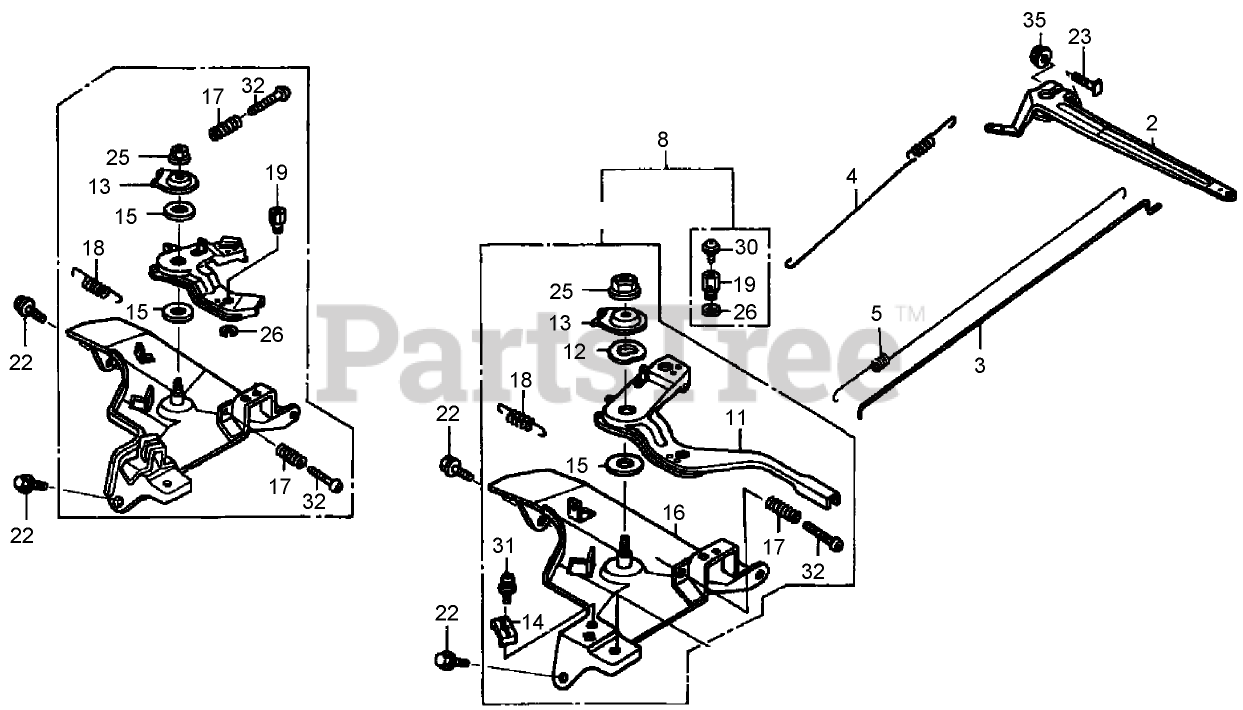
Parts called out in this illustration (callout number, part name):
2	ARM-GOVERNOR
3	ROD-GOVERNOR
4	SPRING-GOVERNOR
5	SPRING-THROTTLE RETURN
8	CONTROL ASM (REMOTE)
11	LEVER-CONTROL
12	SPRING-LEVER
13	WASHER-CONTROL LEVER
14	Holder-Cable
15	SPACER-CONTROL LEVER
16	BASE-CONTROL
17	SPRING-ADJUSTING, CONTROL
18	SPRING-CABLE RETURN
19	HOLDER-WIRE
22	BOLT-FLANGE (6X12) (C T200)
23	BOLT-ARM, GOVERNOR
25	NUT-SELF-LOCK (6MM)
26	CIRCLIP (5MM)
30	SCREW-PAN (4X6)
31	Screw-Pan (5X16)
32	SCREW-WASHER (5X16)
32	SCREW-PAN (5X32)
35	NUT-FLANGE (6 mm)
